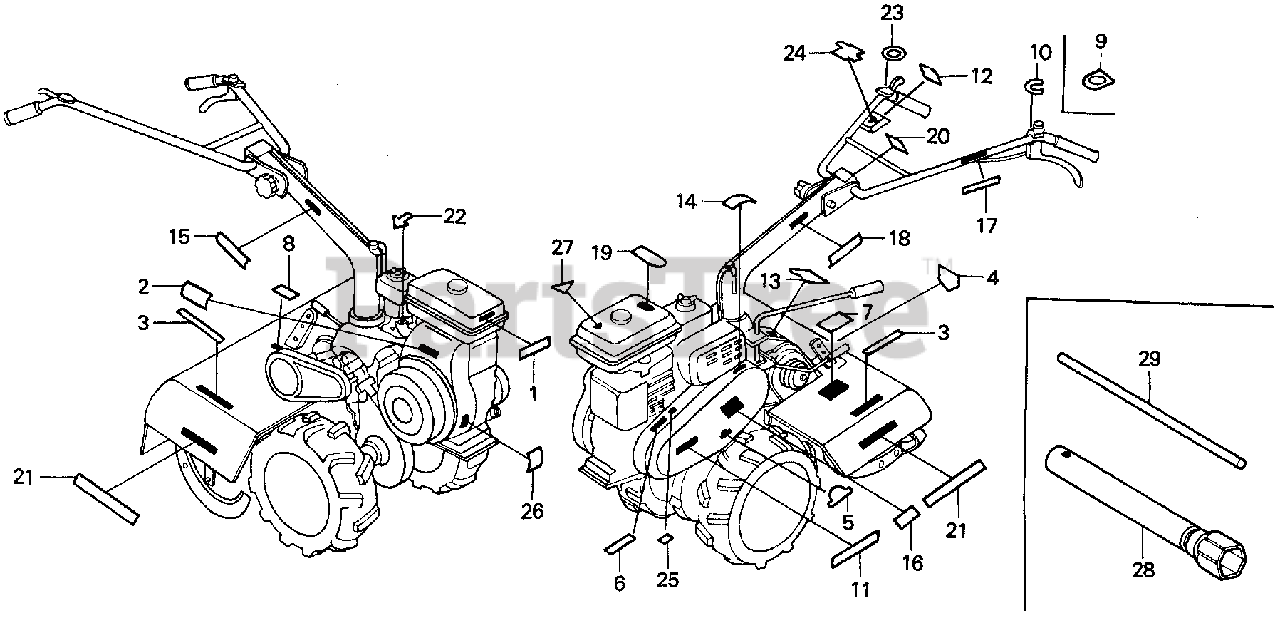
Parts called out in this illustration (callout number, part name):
2	MARK, FAN COVER CAUTION (ENGLISH)
3	LABEL A, HOUSING CAUTION
3	CAUTION A, HOUSING
4	LABEL B, HOUSING CAUTION (ENGLISH)
4	LABEL B, HOUSING CAUTION
4	LABEL C, HOUSING CAUTION
7	MARK, ROTARY CLUTCH
10	MARK, BELT COVER (FR700)
13	MARK, CHANGE
14	CAUTION, BELT COVER (ENGLISH)
15	CAUTION, OPERATOR
15	CAUTION, OPERATOR (ENGLISH)
16	LABEL, BELT ADJUSTING CAUTION (ENGLISH/FRENCH)
18	PLATE, EX. GAS CAUTION
18	LABEL, EX. WARNING
19	LABEL, FIRE CAUTION
19	MARK A, CAUTION (ENGLISH/FRENCH)
20	MARK, COLUMN DASHBOARD
21	MARK (HONDA)
22	MARK, CHOKE
27	MARK, OIL CAUTION
28	WRENCH, SPARK PLUG (NOT AVAILABLE)
29	HANDLE, BOX WRENCH (NOT AVAILABLE)
